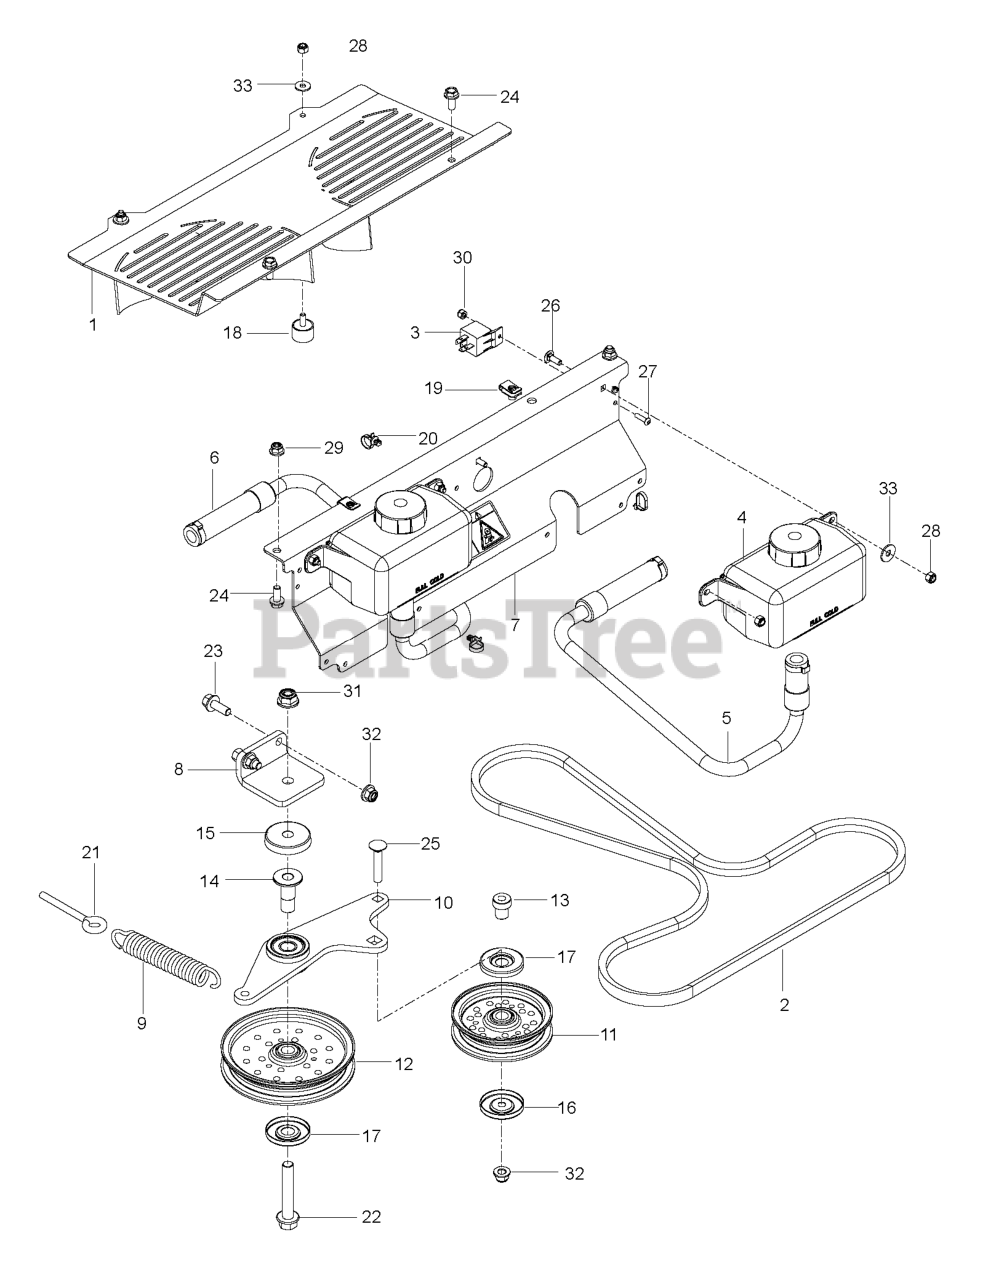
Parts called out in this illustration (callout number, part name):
1	SHIELD, FAN
2	BELT, BX, 72.3
4	HG_TANK, EXPANSION
5	HOSE, EXPANSION TANK, RT
6	HOSE, EXPANSION TANK, LT
7	MOUNT, EXPANSION TANK, BLK
8	MOUNT, IDLER ARM, BLACK
9	SPRING, EXTENSION
10	ARM, IDLER W/BEARING
11	IDLER PULLEY
12	IDLER, FLAT, 5.5"
13	PIVOT, IDLER
14	BUSHING, PIVOT
15	SHIELD, DUST
16	DUST SHIELD
17	SHIELD, DUST
18	BUMPER, MALE STUD, 1/4-20
19	U-CLIP 5/16-18 NUT RETAINER
20	Tie Wrap W/Clip
21	EYE BOLT 5/16 X 3.50
22	HFFS 1/2-13 X 3 GD 5 ZD
23	HHFS 3/8-16 X 1 GRD 5 ZD
24	HHFS 5/16-18 X 3/4
25	RHSNB 3/8C X 2
26	RHSNB 1/4C X 3/4
27	SCR #10-24 X .75 SKT HD BLK
28	NUT.1/4-20.HEX.NYLOC.ZD
29	5/16-18 NYLOC FLANGE NUT
30	NUT 10-24 NYLOC
31	NUT, 1/2-13 HEX FLG NYLOC ZD
32	NUT 3/8-16 HEX FLG NYLOC ZD
33	WASHER 1/4 FLAT
